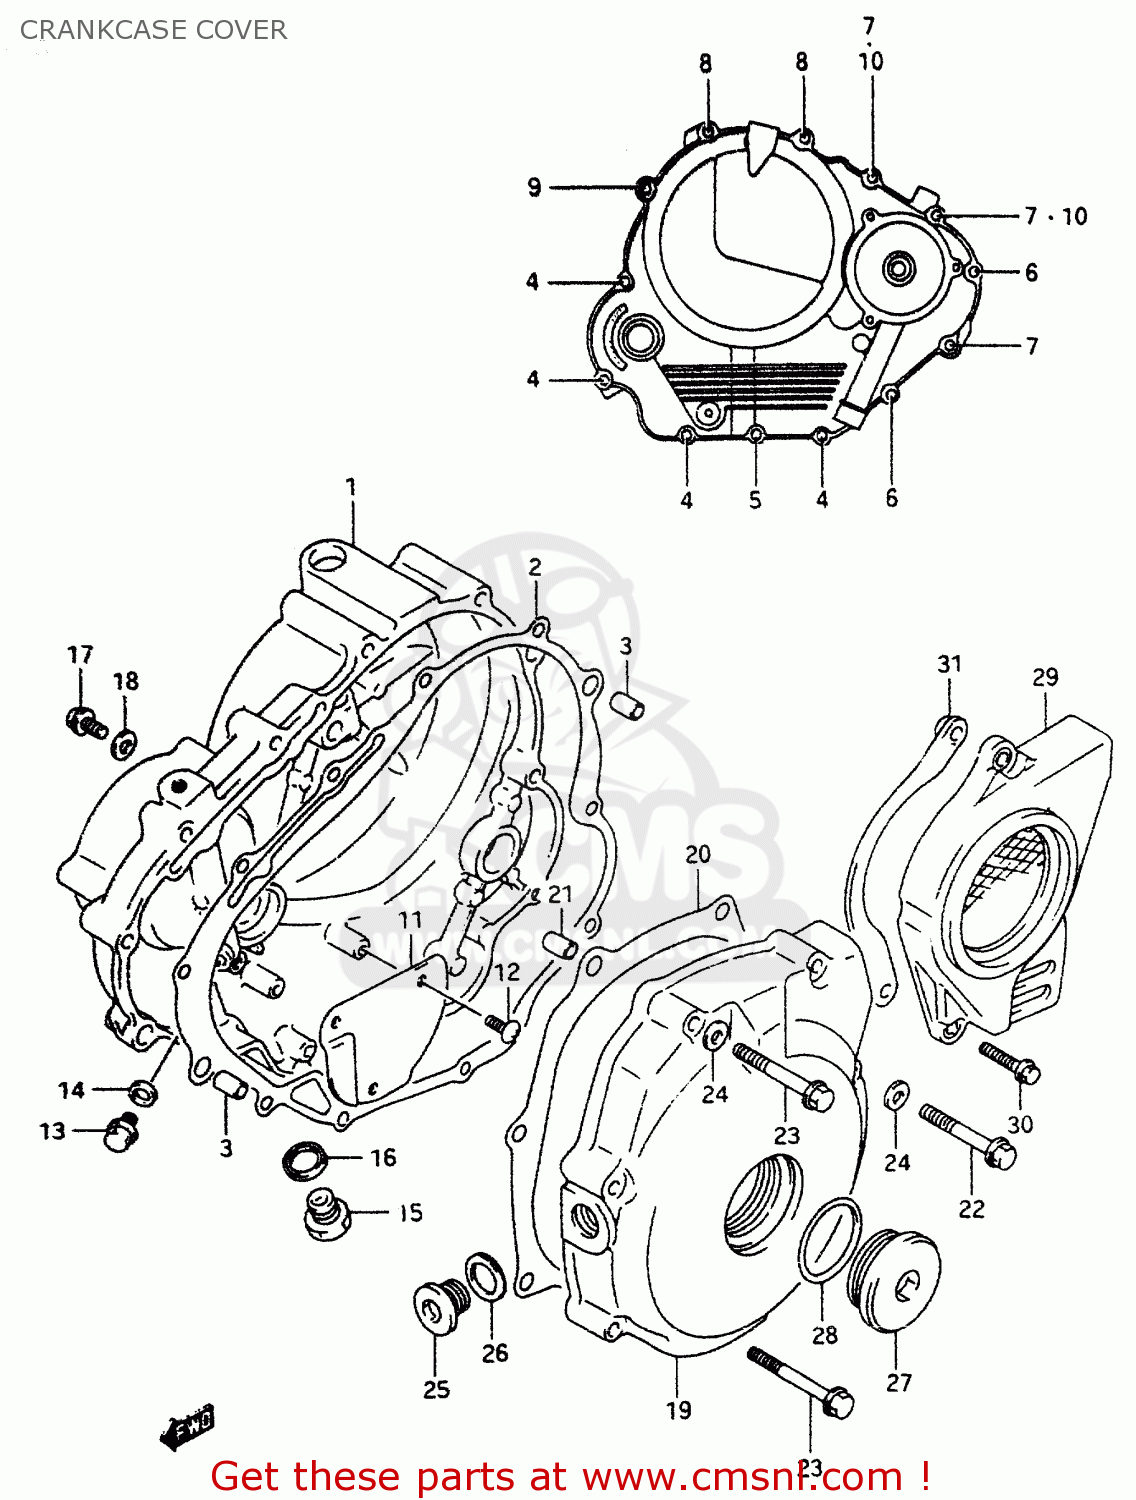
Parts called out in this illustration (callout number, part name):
1	COVER,CLUTCH
2	GASKET,CLUTCH COVER (NAS)
3	PIN
4	SCREW
5	BOLT,G/S SWITC
6	BOLT
7	BOLT
8	BOLT
9	BOLT
10	GASKET(5.8X11X1.2) (NAS)
11	SEPARATOR,OIL RETURN
12	SCREW
13	BOLT(6X8)
14	GASKET(6.2X11X1).2 (NAS)
15	PLUG(10X6.8)
16	GASKET(10X14X3.6) (NAS)
17	SCREW (6X10)
18	GASKET(5.8X11X1.2) (NAS)
19	COVER,MAGNETO
20	GASKET,MAGNETO COVER (NAS)
21	PIN
22	BOLT
23	BOLT
24	GASKET(5.8X11X1.2) (NAS)
25	PLUG,14X12
26	GASKET(13.8X18.8X4.8) (NAS)
27	PLUG(SILVER)
28	O RING(D:3.1,ID:32.7)
29	COVER,ENGINE SPROCKET
30	SCREW
31	PLATE,FR CHAIN GUIDE
